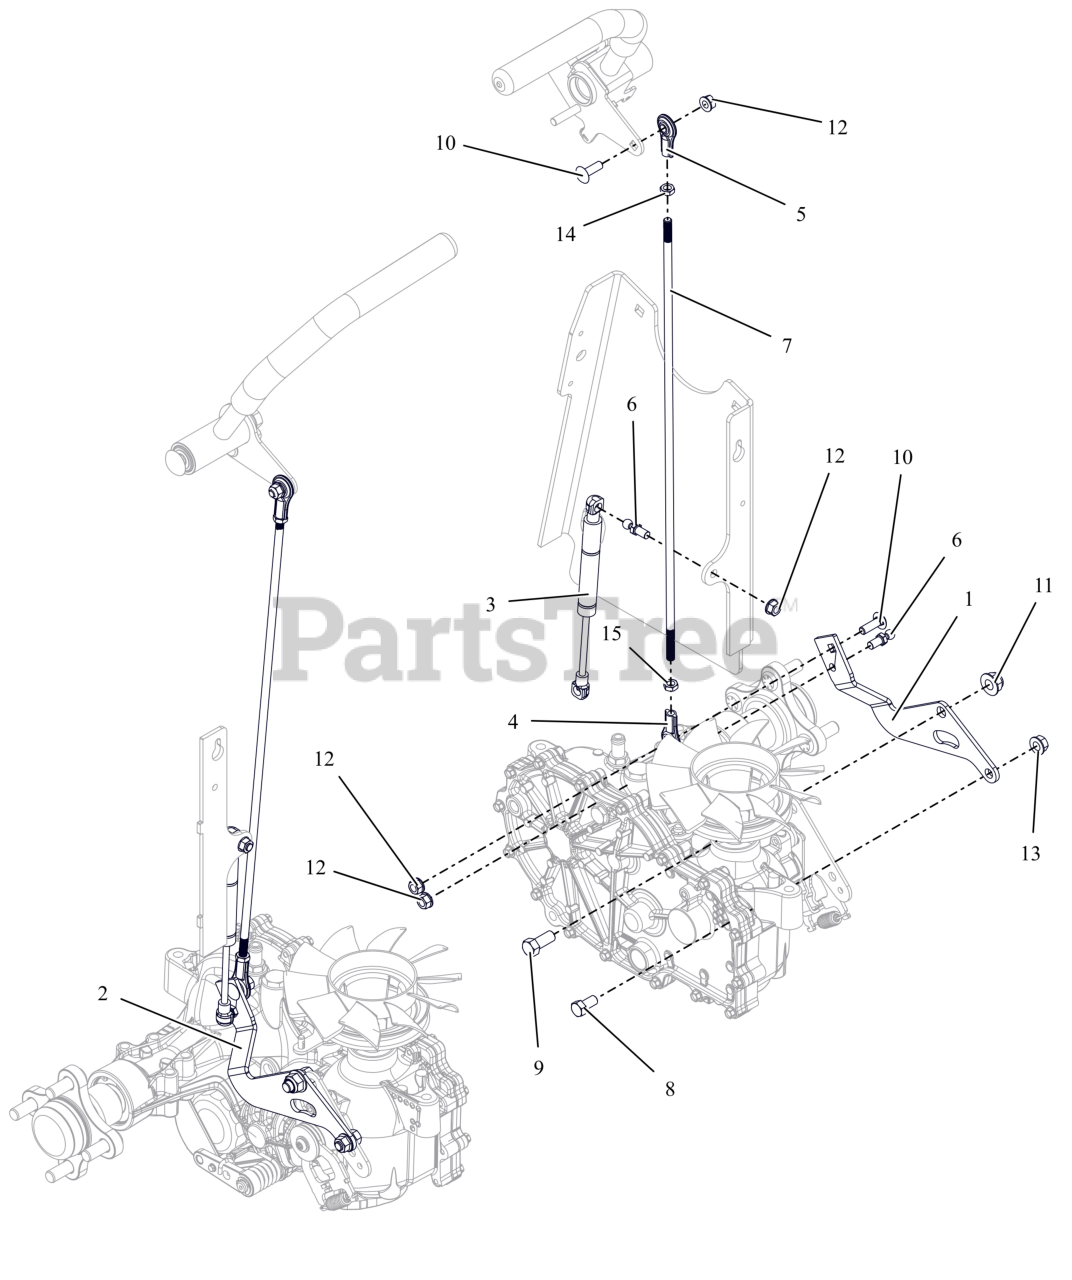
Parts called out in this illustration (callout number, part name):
1	ARM, LH DRIVE CONTROL
2	ARM, RH DRIVE CONTROL
3	DAMPER, CONTROL
4	ALIGNABALL, 5/16 RH THREAD
5	ALIGNABALL, 5/16 LH THREAD
6	STUD- BALL
7	ROD, STEERING
8	BLT,HEX .38-16X.75 G5 ZCC
9	BLT, HEX 0.4375-14X1 GR5 ZCC
10	BLT,RHSSN .31-18X1.00 G5 ZCC
11	NUT,NYL-FLG .44-14 GF ZCC
12	NUT,LK-CTR-FLG .31-18 GF ZCC
13	NUT-LK-CTR-FLG .375-16 GF ZCC
14	NUT, JAM-LH .312-24 ZCC
15	NUT-JAM .312-24 ZCC
